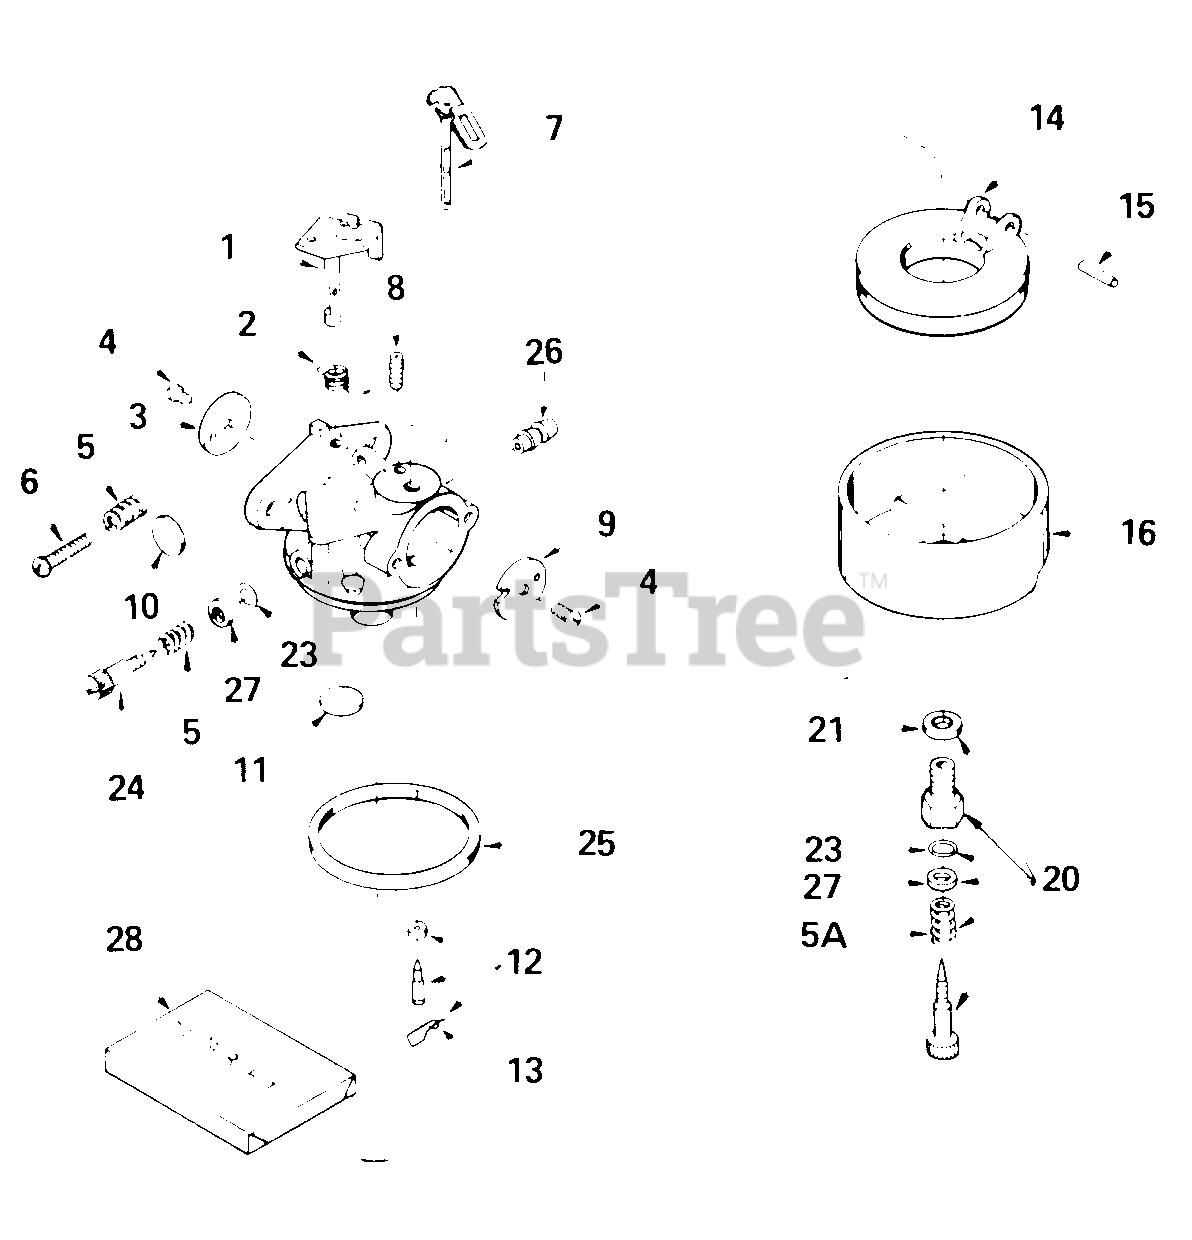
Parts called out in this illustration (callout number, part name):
1	Shaft & Lever Ass'y., Throttle
2	Spring, Throttle Return
3	Shutter, Throttle
4	Screw, Throttle & Choke Shutter
5	Spring, Regulating Screw
5A	Spring, Main Adjustment Screw
6	Screw, Idle Regulating
7	Shaft & Lever Ass'y., Choke
8	Spring, Choke Positioning
9	Shutter Choke
10	Plug, Welch
11	Plug, Welch
12	Inlet Needle, Seat & Clip Ass'y.
13	Clip, Inlet Needle
14	Float, Carburetor
15	Shaft, Float
16	Bowl, Float
20	Adjustment Screw Ass'y., Main
21	Gasket, Bowl-to-Body
23	I O- Ring, Adjustment Screw
24	Screw, Idle Adjustment
25	Gasket, Bowl-to-Body
26	Fitting, Fuel Inlet
28	Repair Kit
